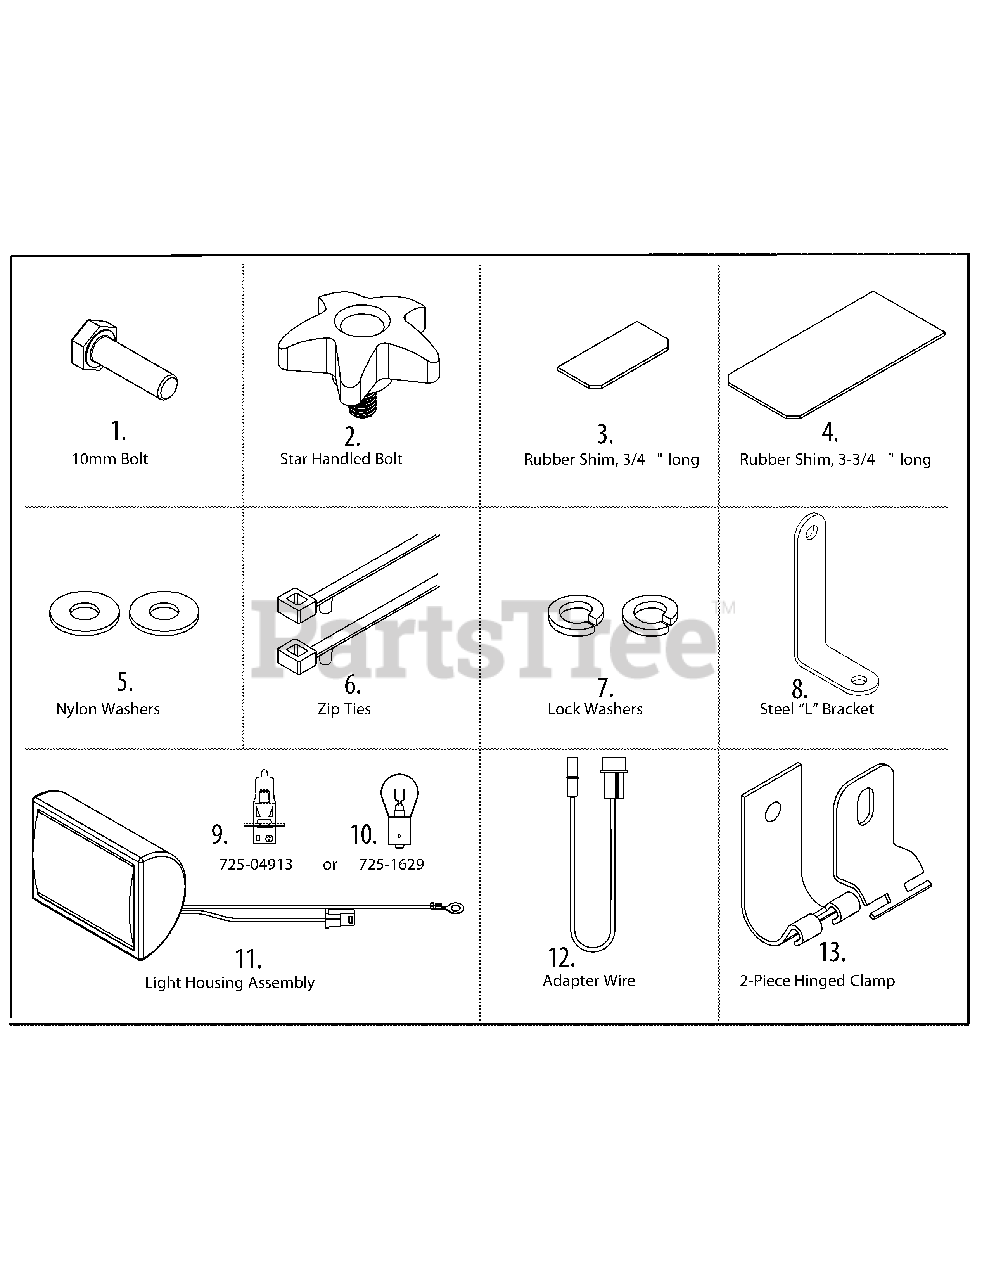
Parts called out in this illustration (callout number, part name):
2	Star Handled Bolt
3	Rubber Shim 3/4" Long
4	Rubber Shim 3-3/4" Long
5	Nylon Washers
6	Zip Ties
7	Lock Washers
8	Steel "L" Bracket
9	Light Bulb 15w
10	Light Bulb 12Volt
11	Light Housing Assembly
12	Adapter Wire
13	2-Piece Hinged Clamp
